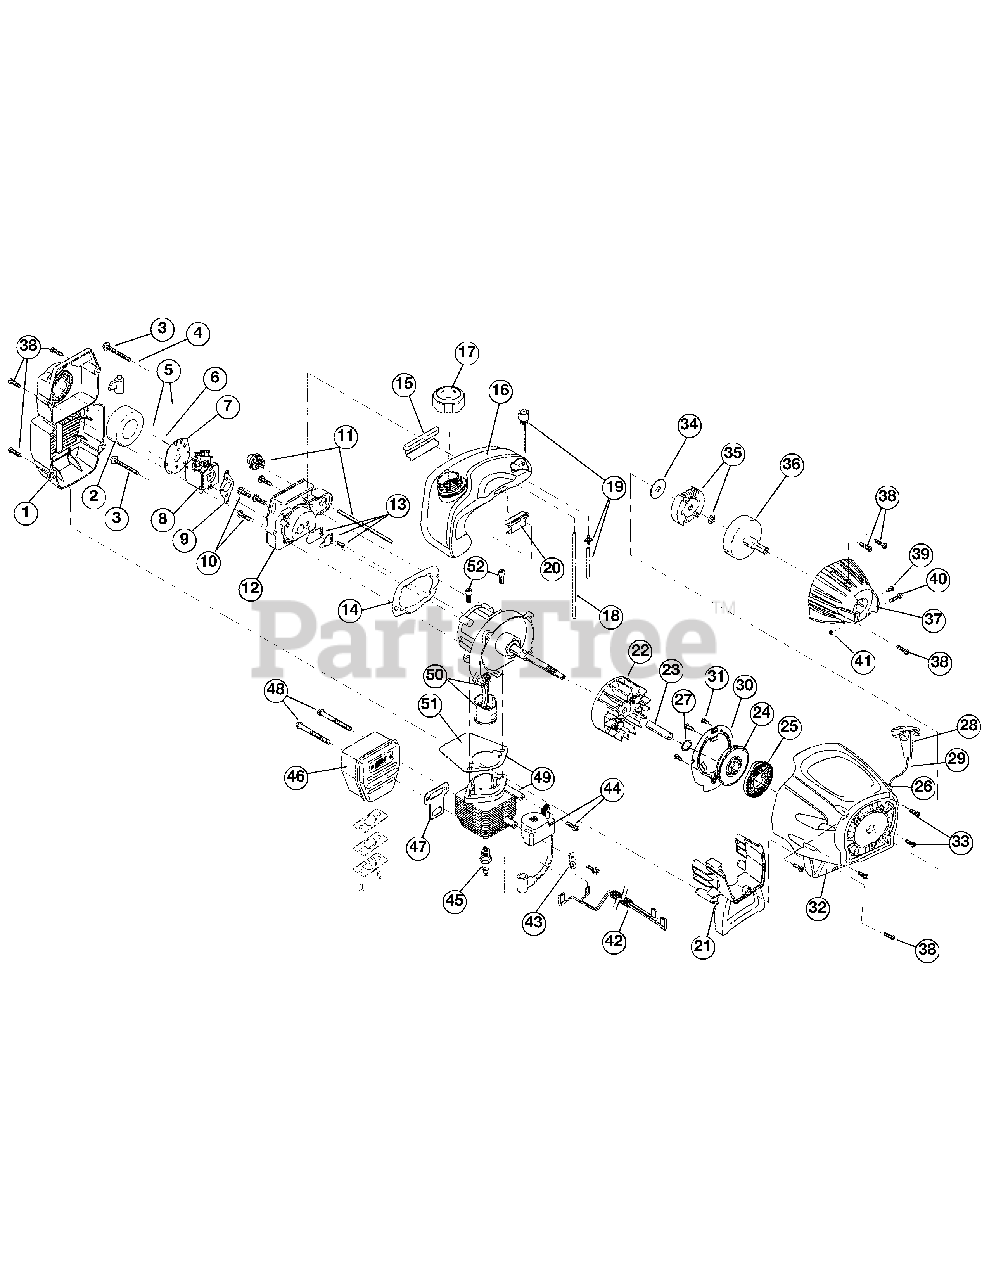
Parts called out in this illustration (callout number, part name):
1	Air Cleaner Cover Assembly (includes 2 & 38)
2	Air Cleaner Filter
3	Carburetor Mounting Screw Assembly
4	Wavey Washer
5	Choke Knob w/Screw
6	Choke Lever (includes 5)
7	Choke Plate (includes 6)
8	Carburetor Assembly (includes 9 & 19)
9	Carburetor Gasket
10	Carb Mount Screw
11	Primer & Hose Assembly
12	Carb Mount Assembly (includes 10, 13 & 14)
13	Reed Assembly
14	Carburetor Mount Gasket
15	Rear Mounting Pad
16	Fuel Tank Assembly (includes 17-19)
17	Fuel Cap Assembly
18	Fuel Return Line
19	Fuel Line Assembly
20	Front Mounting Pad
21	Shroud Extension & Stand (includes 38)
22	Flywheel Assembly
24	Recoil Pulley Assembly (includes 27 & 29)
25	Recoil Spring
26	Rope Guide
27	Pulley Retainer
28	Pull Handle
30	Pressure Plate Assembly (includes 31)
31	Plate Screw
32	Starter Housing Assembly (includes 24-31, 33 & 38)
33	Housing Screw
34	Clutch Washer
35	Clutch Rotor Assembly
36	Clutch Drum Assembly
37	Clutch Cover Assembly (includes 38-41)
38	Cover Screw
39	Anti-Rotation Screw
40	Clamping Screw
41	Clamping Nut
42	Wire Leads and Sleeve
43	Ground Tab
44	Module Assembly
45	Spark Plug
46	Muffler Assembly (includes 47, 48 & spark arrestor)
47	Exhaust Gasket
48	Muffler Mounting Bolts
49	Cylinder Assembly (includes 51 & 52)
50	Piston and Rod Assembly
51	Cylinder Gasket
52	Cylinder Bolt
